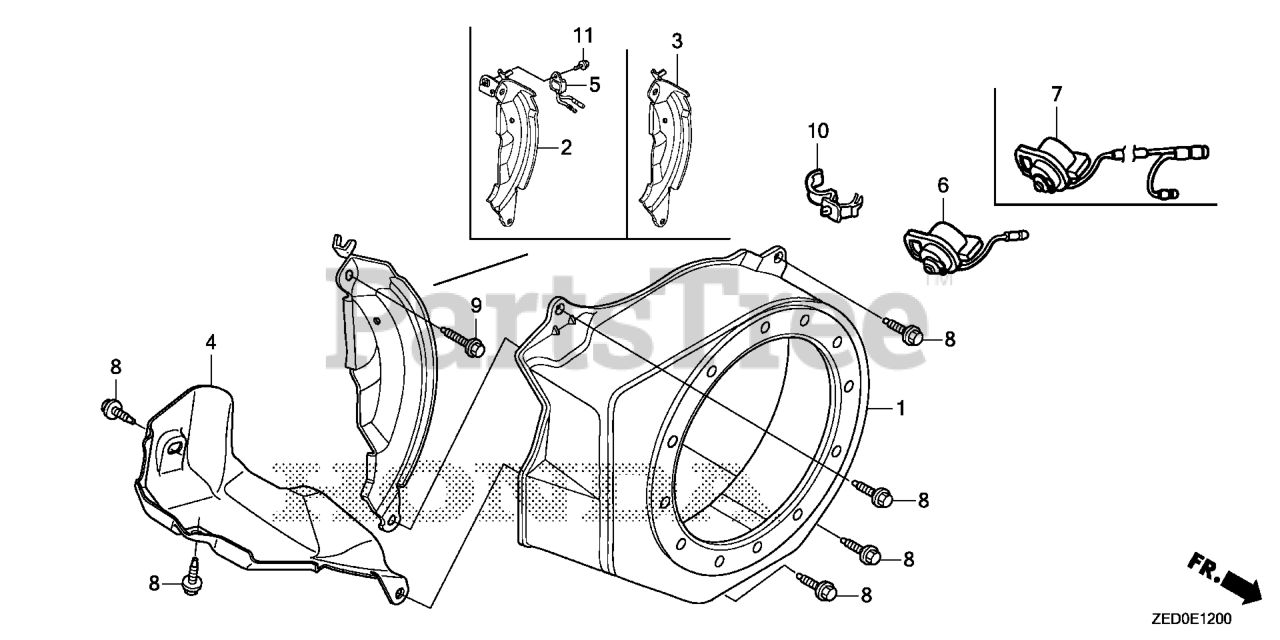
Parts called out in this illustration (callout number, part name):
1	COVER, FAN *R280* (POWER RED)
1	COVER, FAN *NH1* (BLACK)
2	PLATE, SIDE (OIL ALERT)
5	ALERT UNIT, OIL (CHONGQING LIHUA)
5	ALERT UNIT, OIL
7	SWITCH ASSY., ENGINE STOP (TOYO DENSO)
7	SWITCH ASSY., ENGINE STOP (MINDA)
7	SWITCH ASSY., ENGINE STOP
8	BOLT, FLANGE (6X12) (CT200)
9	BOLT, FLANGE (6X20) (CT200)
10	CLIP, HARNESS
11	BOLT, FLANGE (6X8)
